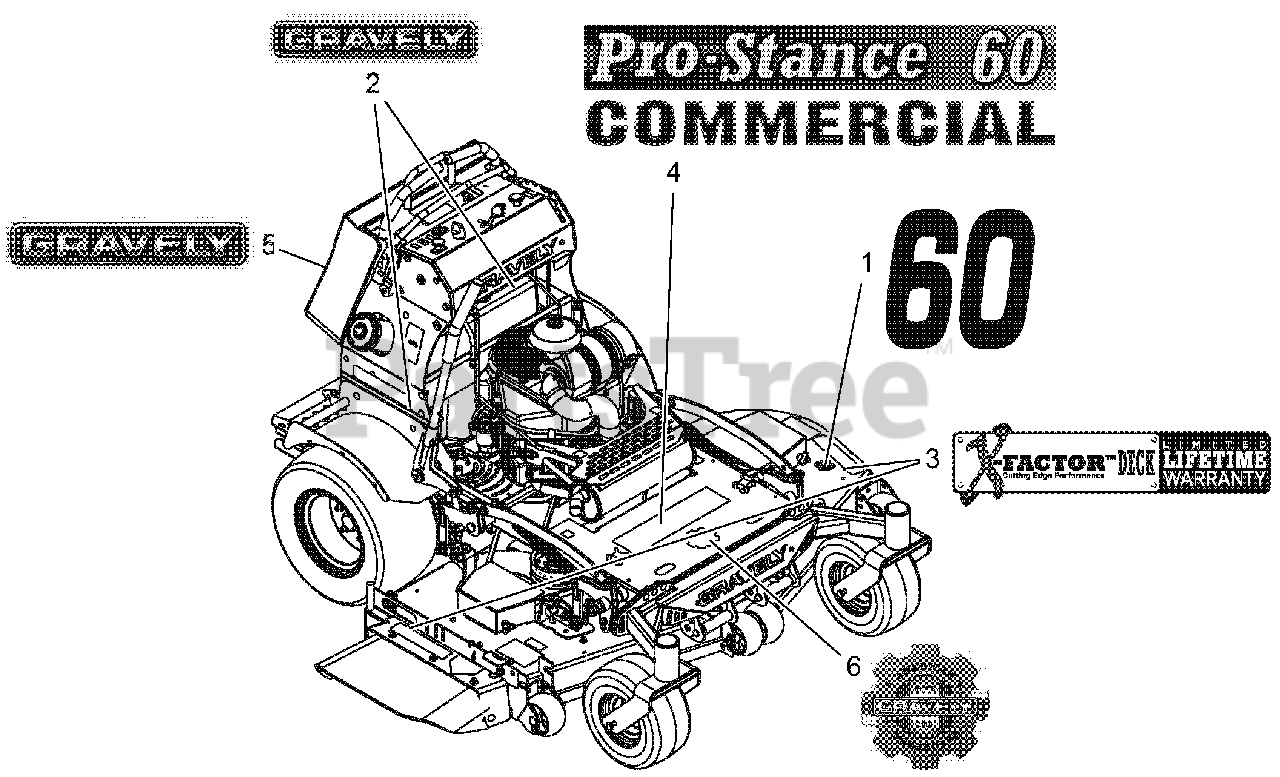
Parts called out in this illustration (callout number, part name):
1	DECAL, 60"
2	DECAL, 9.5" GRAVELY LOGO
3	DECAL, X-FACTOR DECK
4	DECAL, 60" PRO-STANCE SHIELD
5	DECAL, FUEL TANK-GRAVELY
6	DECAL, GRAVELY HERITAGE-LARGE
